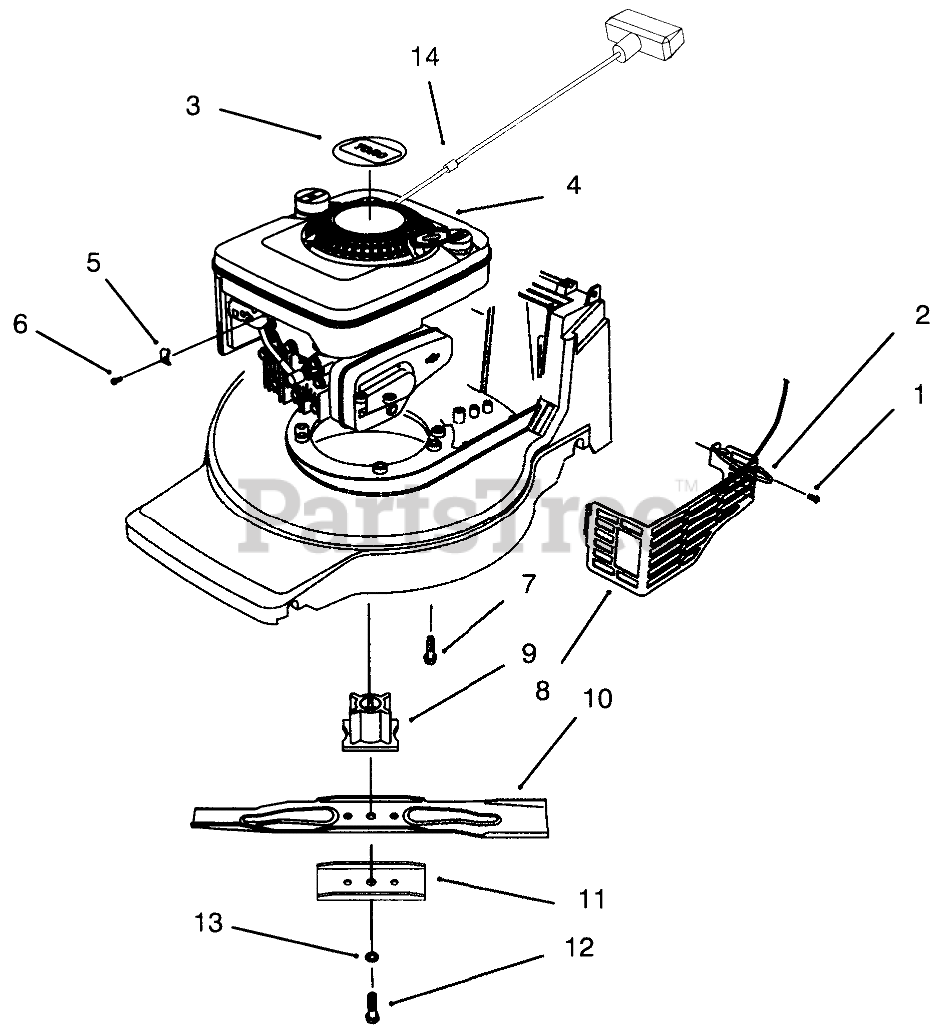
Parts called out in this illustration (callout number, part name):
1	SCREW-HWH
2	TIE-CABLE
3	DECAL - RECOIL
4	Engine-B & S Quantum
5	CLAMP-CASING
6	CLAMP SCREW F/W ENGINE
7	SCREW-HWH
8	SHIELD - MUFFLER
9	BLADE RETAINER - 25 MM
10	Blade
11	Stiffener Blade
12	BOLT-BLADE
13	WASHER-LOCK
14	STOP-ROPE
